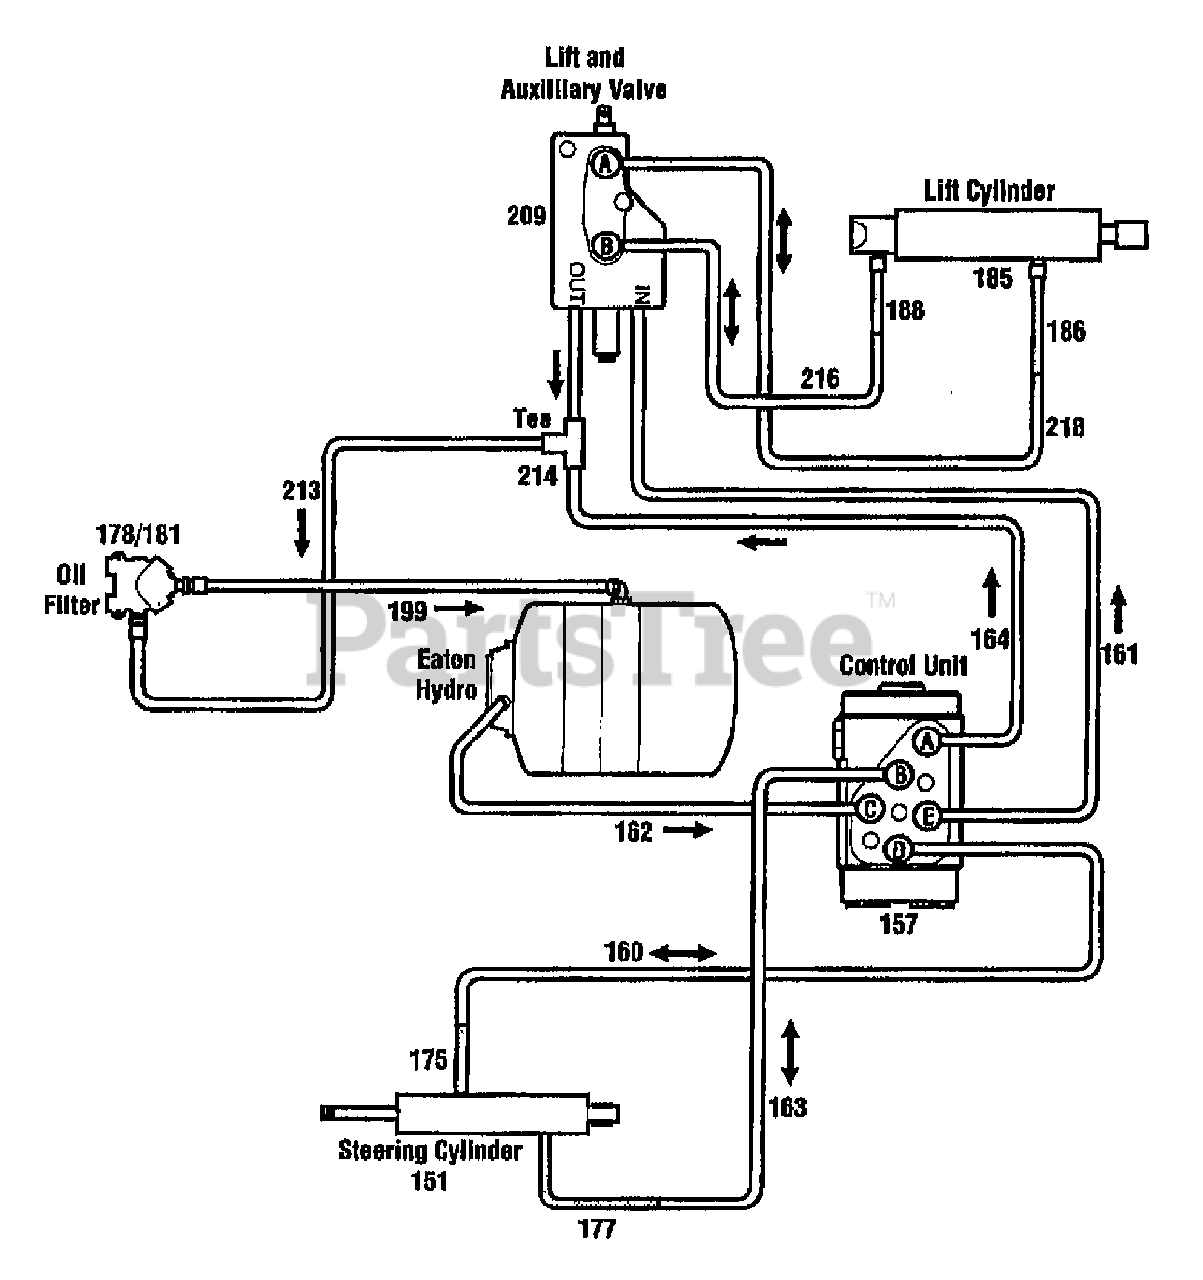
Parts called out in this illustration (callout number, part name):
151	CYLINDER-HYDRAULIC
157	CONTROL UNIT
160	TUBE-HYD RIGHT
161	TUBE-HYD PB VALVE
162	TUBE-HYDRO PRESSURE
163	TUBE-HYD LEFT
164	TUBE-HYD S C U TANK
175	ASSM-HOSE
177	ASSM-HOSE
178	FILTER-OIL
181	MANIFOLD-FILTER
185	ASSM-CYL HYDRAULIC
186	ASSM-HOSE
188	ASSM-HOSE
199	ASSM-RETURN TUBE
209	VALVE-HYDRAULIC
213	TUBE-HYD RETURN
214	TEE-SWIVEL
216	TUBE-HYD VALVE TO ROD
218	TUBE-HYD VALVE TO HEAD
